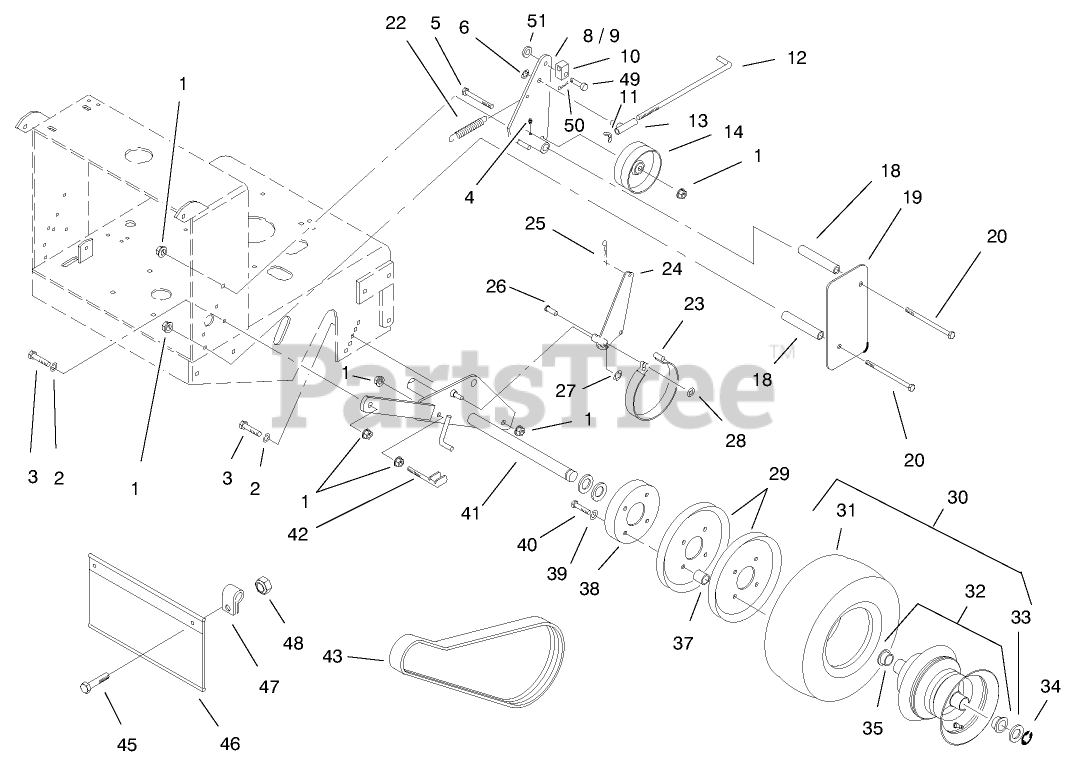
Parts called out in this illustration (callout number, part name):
1	NUT-FLANGE
2	Washer
3	SCREW-HH
4	FITTING-STRAIGHT
5	SCREW-HH
6	Ring
8	Idler Arm ASM LH
9	Idler Arm ASM RH
10	FITTING-ROD
11	Wingnut
12	Brake Rod
13	Swivel
14	Idler-Wheel Drive
18	Idler
19	Shield
20	SCREW-HH
22	Spring-Extension
23	Band-Brake
24	Brake Arm ASM
25	PIN-COTTER
26	Pin
27	Ring-Snap
28	Nut
29	Sheave
30	WHEEL AND TIRE ASM
31	Tire
32	Assembly-Wheel
33	Spacer
33	Spacer-18 GA
34	Ring,Snap E
35	Bearing
37	Spacer
38	Drum-Brake
39	WASHER-LOCK
40	SCREW-HH
41	Axle ASM
42	Scraper
43	Belt-Drive
45	SCREW-HH
46	Shield-Trailing
47	CLAMP-R
48	NUT-LOCK NI
49	PIN-CLEVIS
50	PIN-COTTER
51	WASHER-PLAIN
